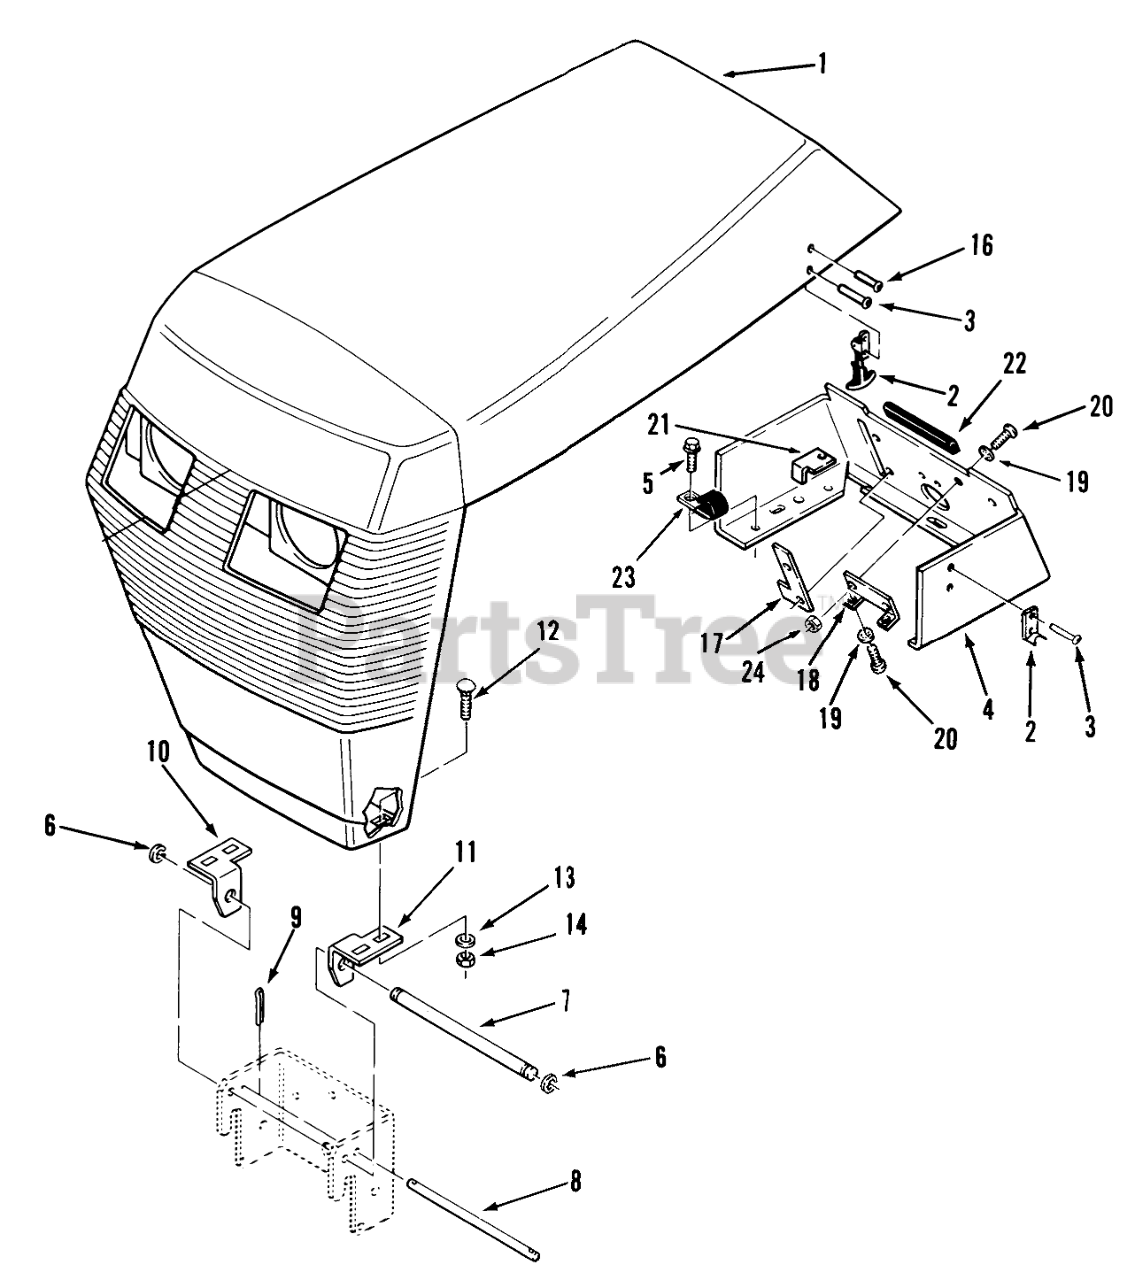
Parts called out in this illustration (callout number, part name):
1	Hood
1	Hood 312-A,418-8,418-A
2	Hood Latch (includes 109236 Handle Ass-y & 109237 Latch Keeper)
3	RIVET -4
4	Console
4	CONSOLE B
4	Console 310-8
5	SCREW
6	RING-RETAINING
7	GRILL PIVOT ROD
8	ROD-HOOD STOP
9	Cotter Pin
10	BRKT-GRILL PIVOT R
11	BRKT-GRILL PIVOT R (NS)
12	Bolt-Carriage
14	Nut
16	RIVET
17	STOP THROTTLE
18	BRACKET
19	Washer-Lock
20	SCREW-PAN
21	STOP-PTO
22	EDGING-CONSOLE
23	J-CLIP
24	Nut
